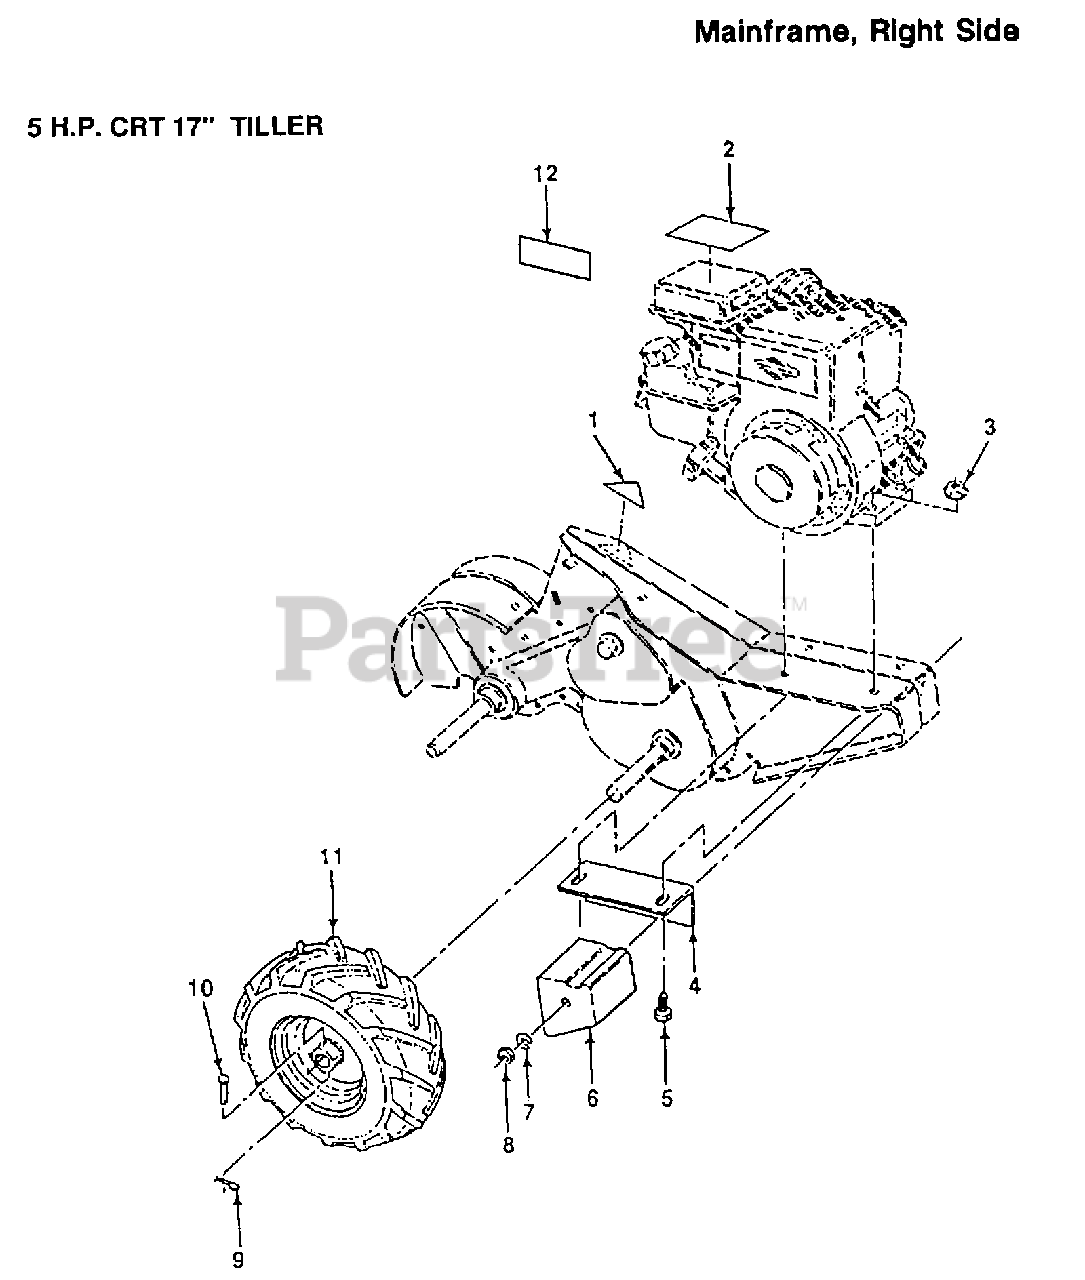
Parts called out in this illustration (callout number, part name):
2	DECAL TI
4	BRACKET RH CRT
5	BOLT.HEX.5/16-1.5
6	COUNTERWEIGHT CRT
7	LOCKWASHER
8	NUT.HEX.3/8-16UNC
9	RETAINER M
11	TIRE.CHV.13X5.0-6
